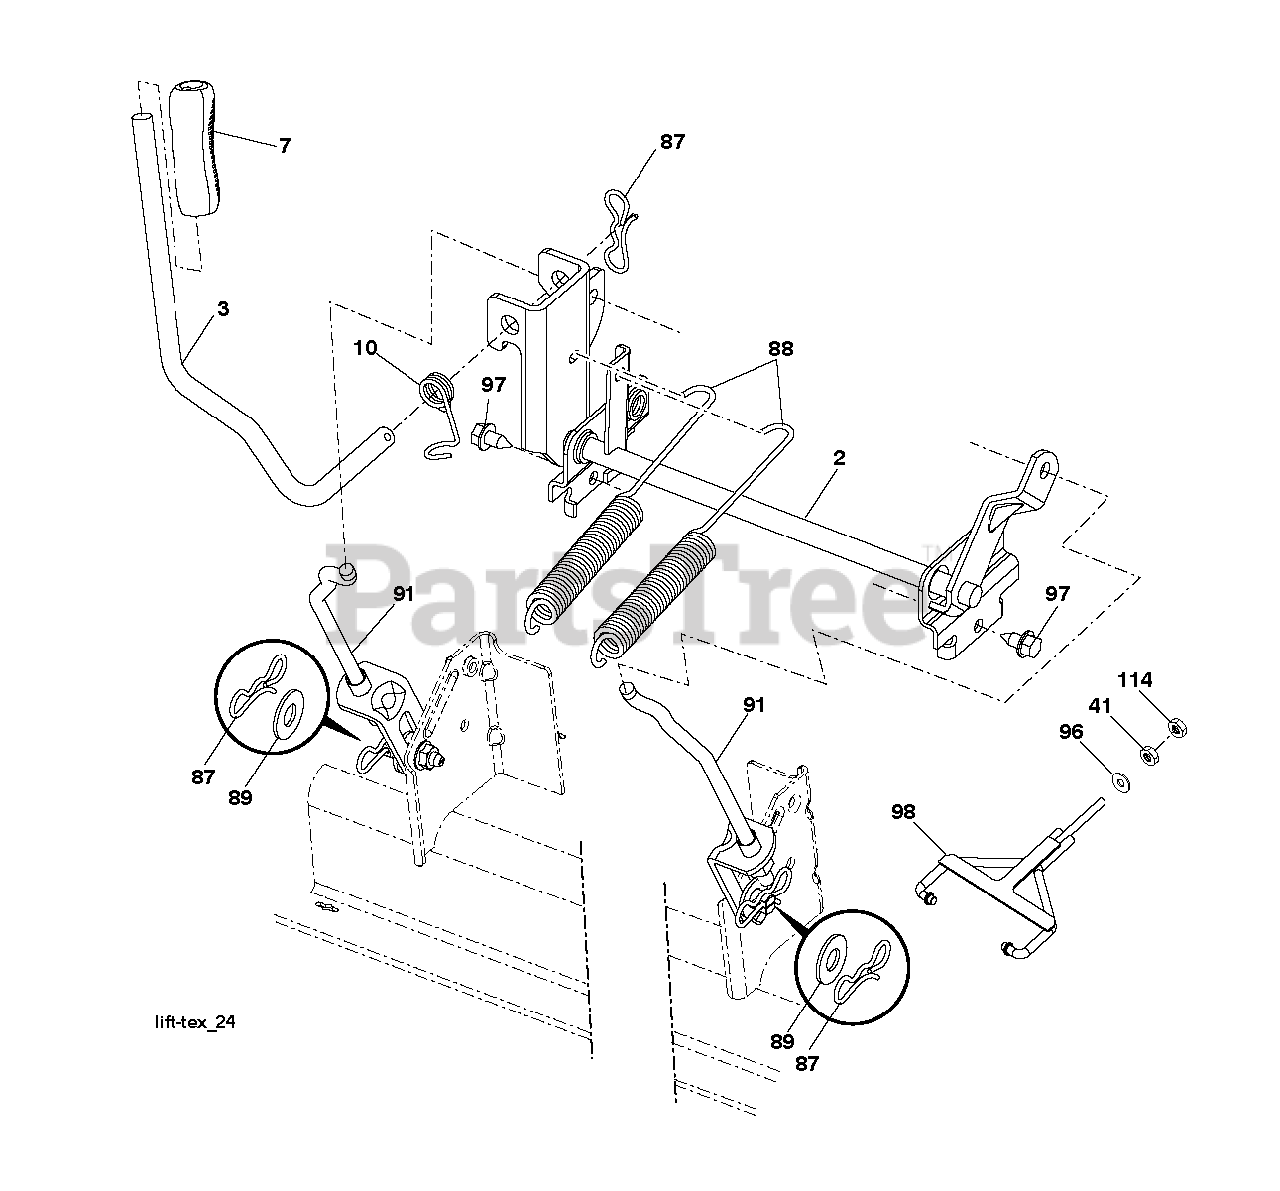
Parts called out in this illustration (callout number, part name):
2	SHAFT.ASM.CROSS.LIFT
3	LEVER.LIFT.HANDLE.GT
7	GRIP.HANDLE.LIFT.PVC.BLACK
10	SPRING.TORSION.LIFT.HANDLE
41	NUT, LIFT LINK 7/16-20
87	PIN.COTTER.7/16.BOW TI.
88	SPRING.LIFT.ASSIST
89	WASHER.CLEAR.ZINC
91	LINK.ASM.LIFT.REAR
96	BUSHING SPHERICAL SUSP. FRONT
97	SCREW, 3/8-16X3/4
98	SUSPENSION WLDT FRONT DECK
114	NUT **
